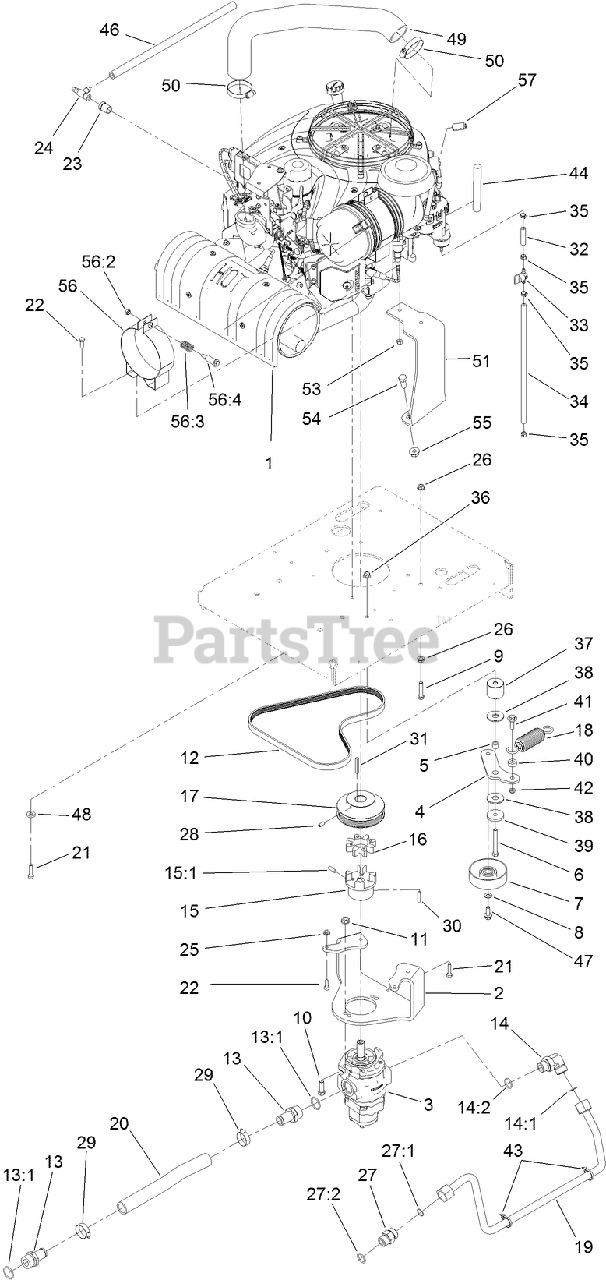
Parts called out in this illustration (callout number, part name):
2	MOUNT-PUMP
3	GEAR PUMP ASM
4	ARM-IDLER
5	BUSHING-LEVER, LIFT
6	SCREW-HH
7	PULLEY-IDLER
8	WASHER-FLAT
9	SCREW-HH
10	SCREW-HH
11	NUT-HF
12	BELT-V
13	FITTING-STR
13:1	O-RING
14	FITTING-ELBOW-90
14:1	O-RING
14:2	O-RING
15	HUB-COUPLER
15:1	SCREW-SET
16	SPIDER
17	PULLEY-ENGINE
18	SPRING-EXTENSION
19	TUBE-HYD
20	HOSE-SUCTION
21	SCREW-HH, LOCK
22	SCREW-HH
23	BUSHING
24	Valve-Drain, Oil
25	NUT-HF
26	NUT-HHF, WHIZ
27	FITTING-STR
27:1	O-RING
27:2	O-RING
28	SCREW-SET, HSH
29	CLAMP-HOSE
30	KEY-SQUARE
31	KEY-SQUARE
32	HOSE-FUEL
33	VALVE-FUEL
34	HOSE-FUEL
35	CLAMP-HOSE
36	NUT-HF, NI
37	SPACER-IDLER
38	WASHER-FRICTION, COMPOSITE
39	WASHER-PLAIN
40	SPACER
41	SCREW-SHOULDER, HWH
42	NUT-LOCK, NI
43	TIE-CABLE
44	SLEEVE-THERMAL,
47	SCREW-HHF
48	SPACER
49	HOSE-INTAKE,AIR
50	CLAMP-HOSE
51	BRACKET-MOUNT, FILTER
53	NUT-LOCK, NI
54	SCREW-HH
55	NUT-HHF
56	BAND-MOUNTING, AIR CLEANER
56:3	SPRING
56:4	NUT
57	FERRITE-SNAP ON
